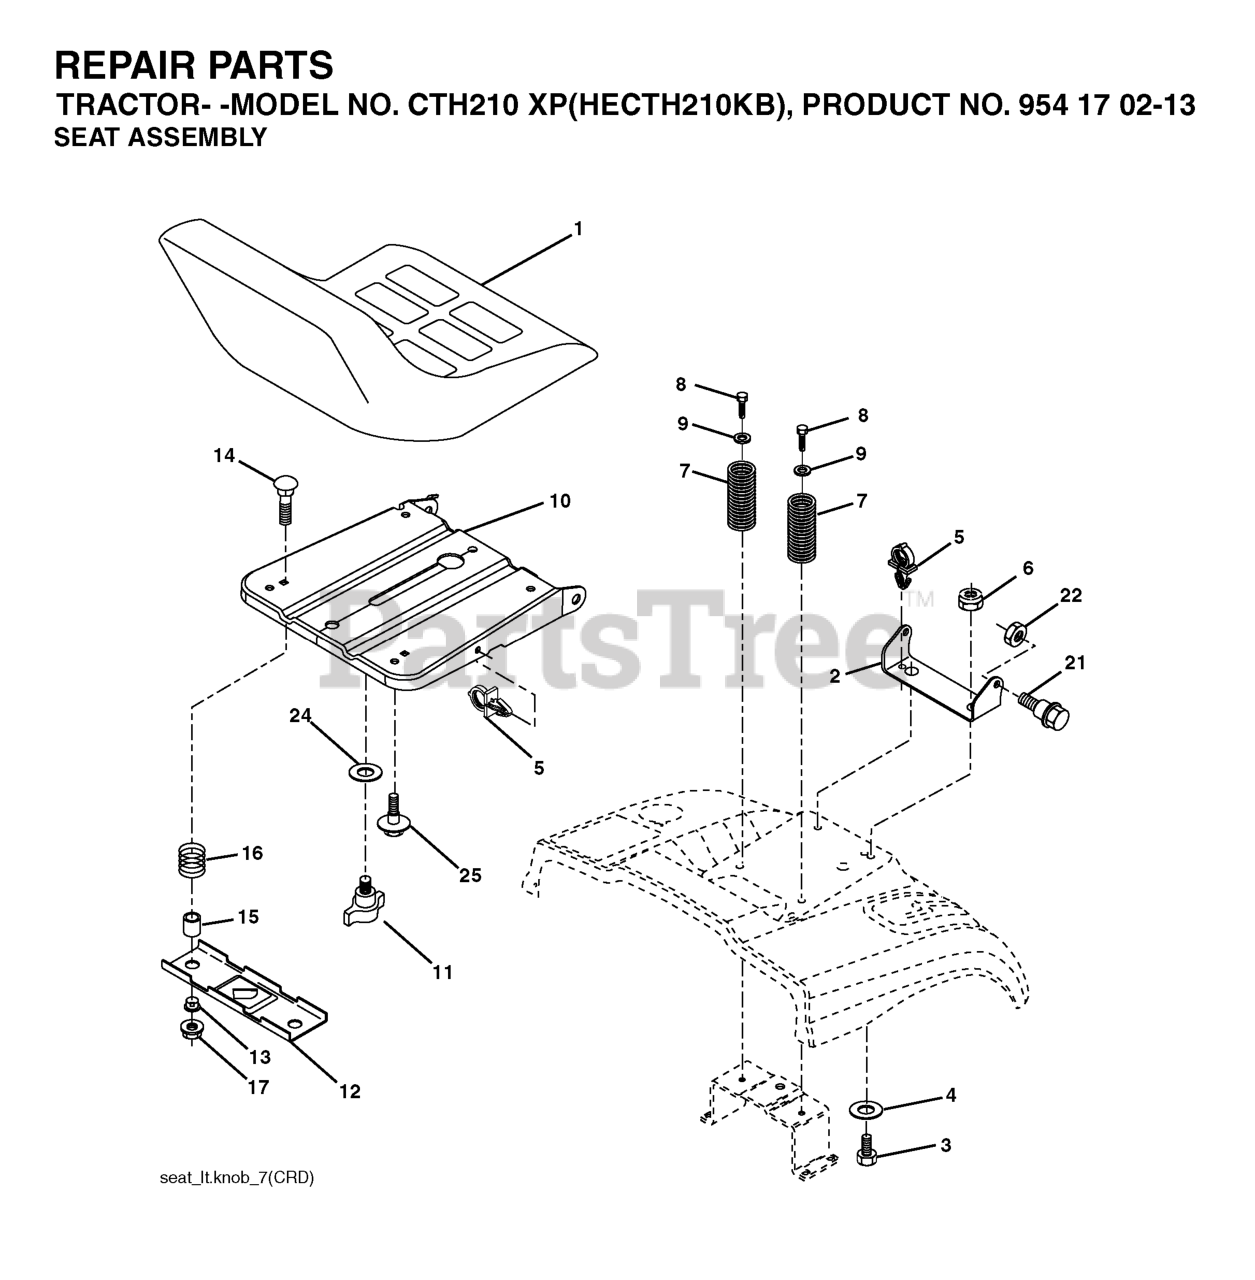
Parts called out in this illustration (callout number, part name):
1	SEAT
2	SEAT PIVOT BRKT
3	BOLT, HEX 3/8-16X1
6	NUT
7	SPRING COMPRESSION
8	SCREW 3/8-16X1
9	WASHER
10	PAN SEAT
11	KNOB.SEAT.ADJ.WINGNUT
12	BRKT SWITCH
14	BOLT.ROUND.HEAD.SQUARE.NECK
15	SPACER SPLIT
16	SPRING COMPRESSED
17	NUT T
21	BOLT.SHOULDER.5/16-18
22	NUT.71038.31-18.HEX.NYLOCK
25	BOLT,SHOULD
